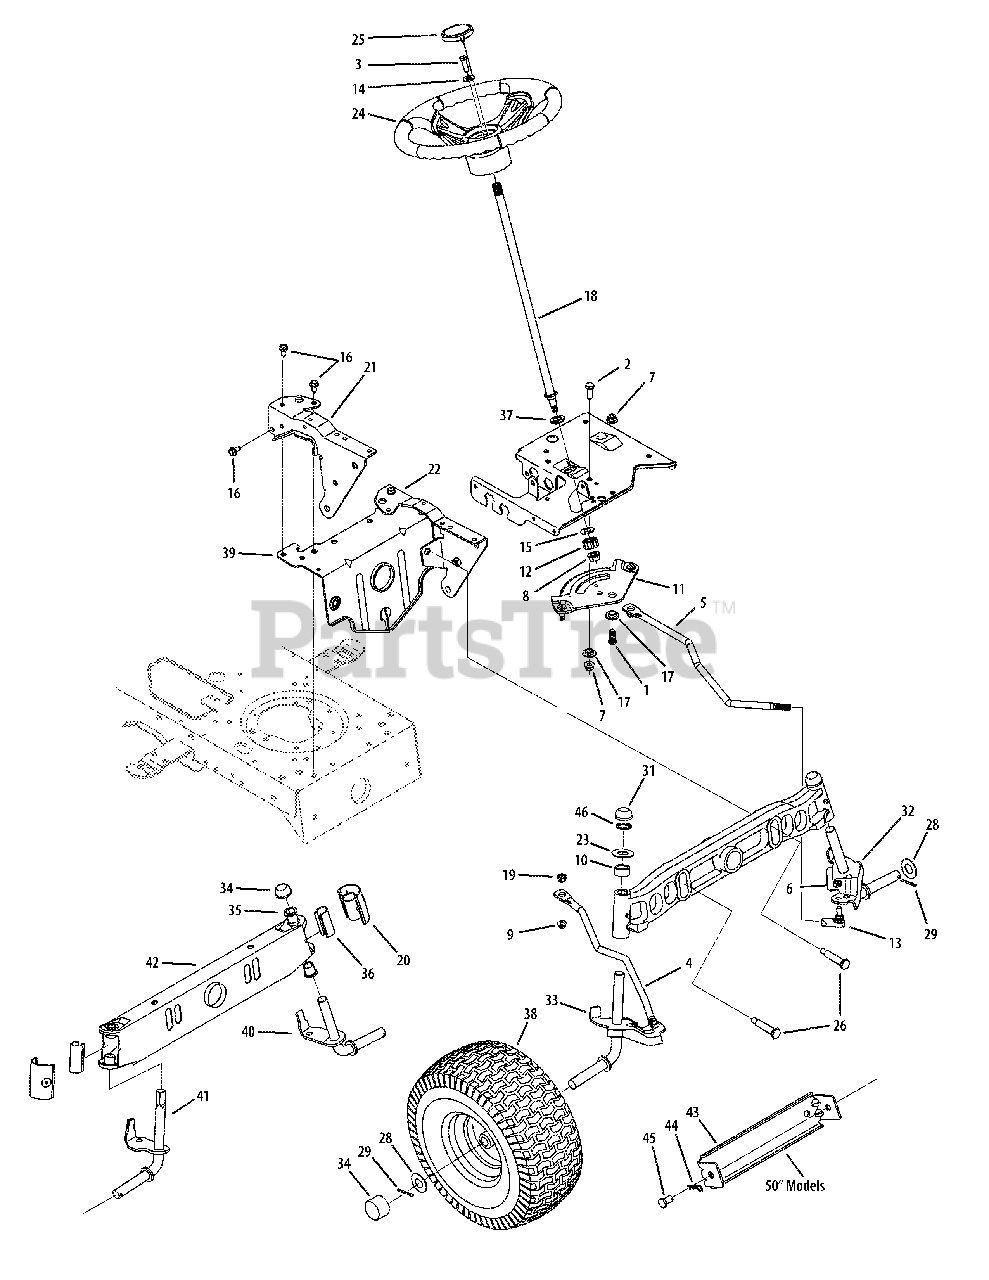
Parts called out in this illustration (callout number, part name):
1	Hex Screw, 3/8-16, 1.00, Gr5
2	Hex Screw, 3/8-16, 1.00, Gr5
3	Hex Screw, 5/16-18, 1.00, Gr5
4	Link, Drag, RH
5	Link, Drag, LH
6	Nut, Hex Lock, 3/8-24
7	Nut, Flange Lock, 3/8-16, Grf
8	Nut, Flange Lock, 7/16-20
9	Nut, Flange Lock, 5/16-18, Gr5
10	Spacer, .71 x .125 x .56
11	Gear, Steering, 11/90 Ratio
12	Gear, Pinion, Steering
13	Ball Joint, 7/16-20, Lock
14	Washer, Flat, .406 x .875 x .105
15	Washer, Flat, .51 x 1.12 x .06
16	Screw, 5/16-18, 0.750
17	Spacer, Shoulder, .38 x 1.00 x .31
18	Shaft, Steering, .625 OD x 24.25
19	Plastic Bushing .380 ID
20	Pivot Bar End Cap w/ fitting
24	Steering Wheel
24	Steering Wheel, Softgrip
25	Steering Wheel Cap
25	Steering Wheel Cap, Sprig Logo
25	Steering Wheel Cap, Tine Logo
26	Shoulder Bolt, .5 x 2.38, 3/8-16
27	Hub Cap, Standard
28	Flat Washer, .781 x 1.59
29	Cotter Pin, 5/32 x 1.25
30	Cast Iron Pivot Bar
31	Push Cap
32	LH Axle Assembly, .750
33	RH Axle Assembly, .750
34	Push Cap, 3/4
35	Flange Bearing
36	Axle End Cap, Standard
37	Hex Flange Bearing
40	LH Axle Assembly, .750
41	RH Axle Assembly, .750
45	Clevis Pin, .50 x .78
46	Nut, Push, 3/4 dia.
